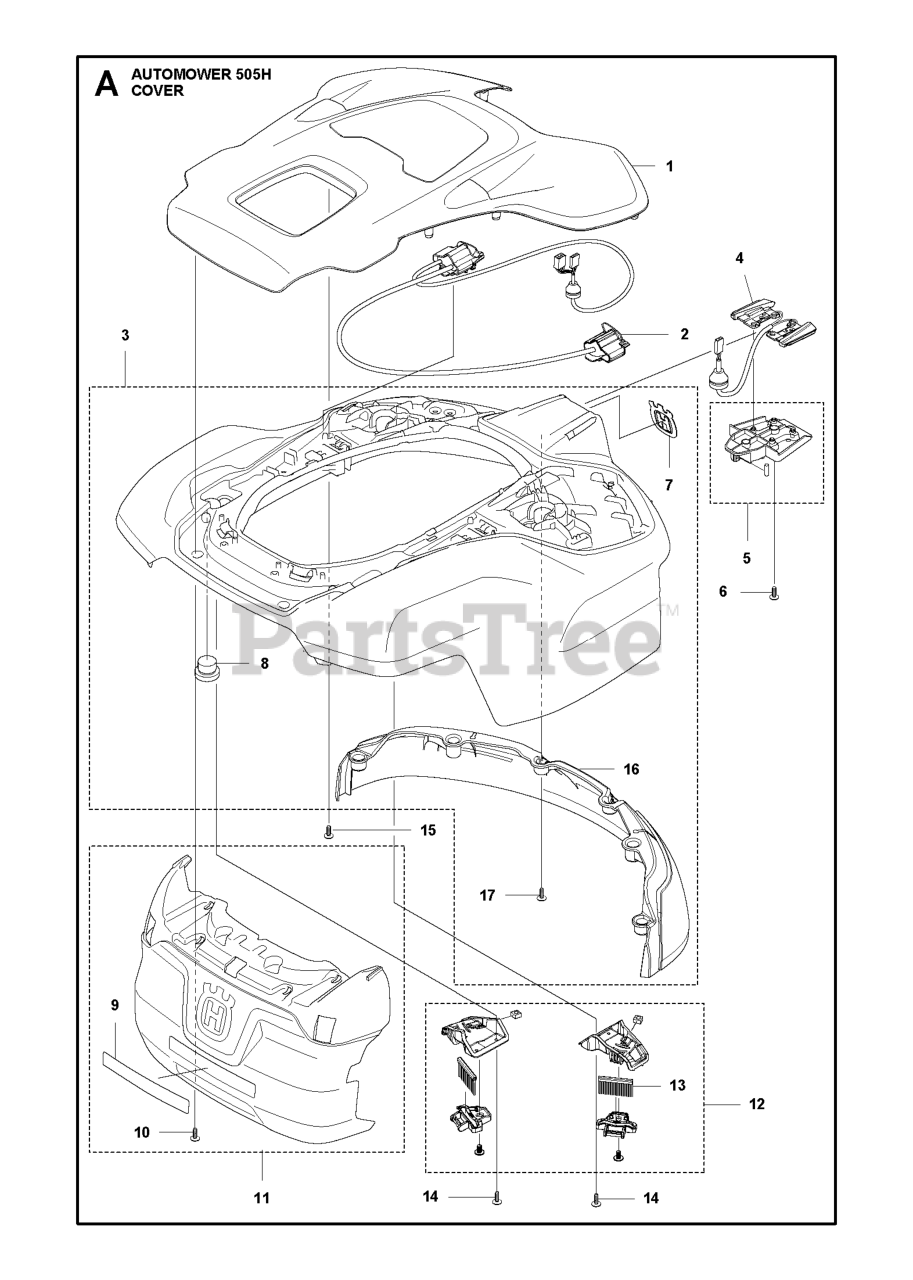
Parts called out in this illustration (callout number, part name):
1	Body
1	BODY KIT SPARE PART TOP COVER
2	WIRING ASSY ULTRASONIC
3	BODY ASSY 430XH, 450XH
4	CABLE ASSY CHARGING PLATE
5	HOLDER ASSY 430XH, 450XH
6	SCREW 14MM
7	DECAL HUSQVARNA CROWN HEIGHT 5
8	CAP SNAPLOC
9	LABEL WARNING P15
10	SCREW ITXPANT
11	BUMPER ASSY 430XH,450XH,550H
12	BRUSH KIT 430/450
13	WHEEL BRUSH REFILL KIT
14	SCREW ITXPANT
15	SCREW ITXPANT
16	BUMPER FRONT
17	SCREW ITXPANT
